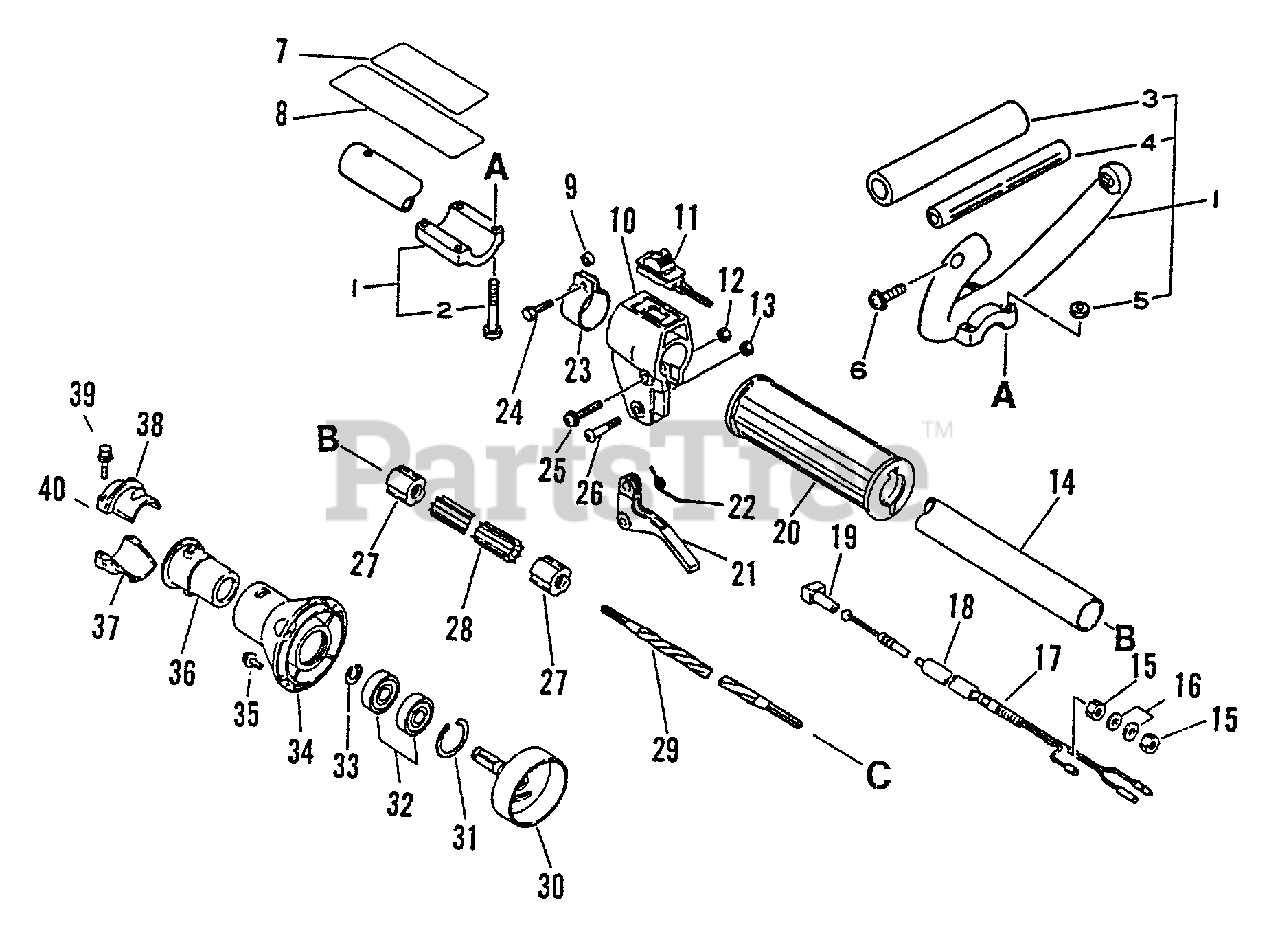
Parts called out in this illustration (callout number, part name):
1	LOOP HANDLE ASSY
2	SCREW 5×35
3	GRIP, HANDLE
5	NUT M5
6	SCREW 5×30
7	LABEL - CAUTION
9	SPACER, GUARD
10	BRACKET, THROTTLE CONTROL
11	IGNITION SWITCH ASSY
12	NUT M5
13	NUT, LOCK M5
14	MAIN PIPE ASSY 25×1500
16	WASHER 6.5×11.5×0.8
17	CABLE, THROTTLE
18	TUBE - VINYL
19	GUIDE, CABLE
20	GRIP
21	TRIGGER, THROTTLE
22	SPRING, THROTTLE
24	BOLT 5×18
25	SCREW 5×30
28	LINER, FLEXIBLE 21.6×1420
29	DRIVESHAFT - FLEXIBLE L= 1522
30	DRUM, CLUTCH
31	RING, SNAP 28
32	BEARING, BALL 6001
33	RING, RETAINING - 12
34	CASE, CLUTCH - GRAY
35	SCREW 5×16
38	HOLDER, MAIN PIPE - UPPER
39	BOLT - 5×25
40	HOLDER KIT
